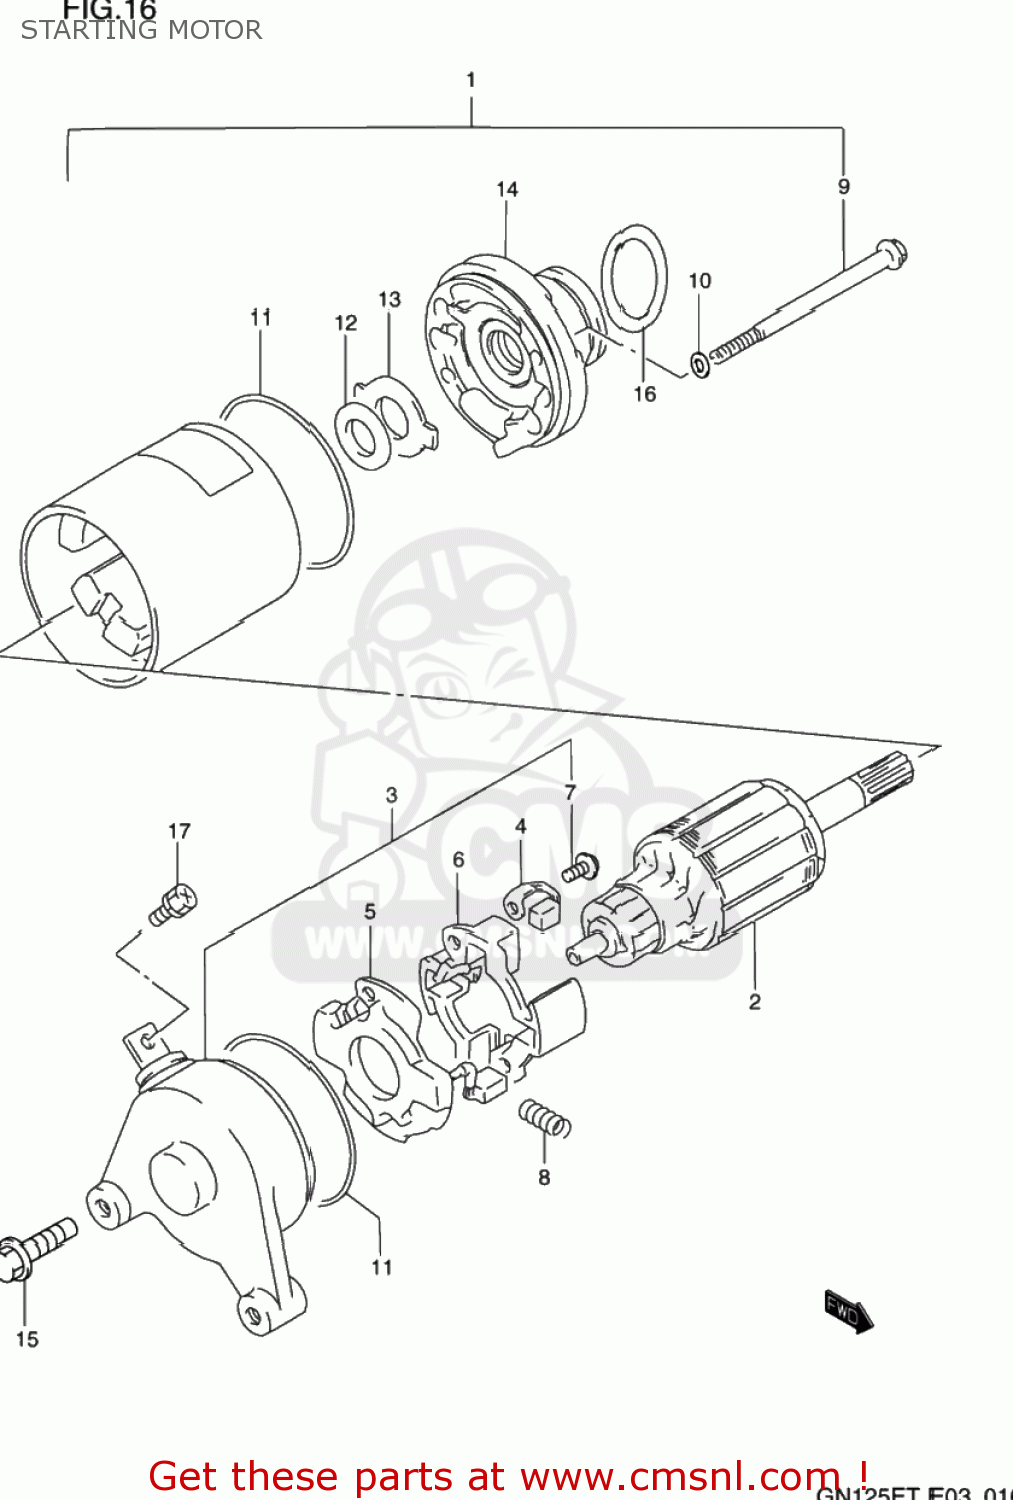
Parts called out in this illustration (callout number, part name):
1	MOTOR ASSEMBLY,STARTING
2	ARMATURE
3	FRAME ASSEMBLY,COMMUTATOR
4	BRUSH
5	BRUSH SUB ASSEMBLY
6	HOLDER,BRUSH
7	SCREW
8	SPRING
9	BOLT
10	O RING
11	O RING
12	SHIM
13	PLATE,LOCK
14	BRACKET
15	BOLT
16	O RING(D:3,ID:24.5)
17	SCREW(5X8)
